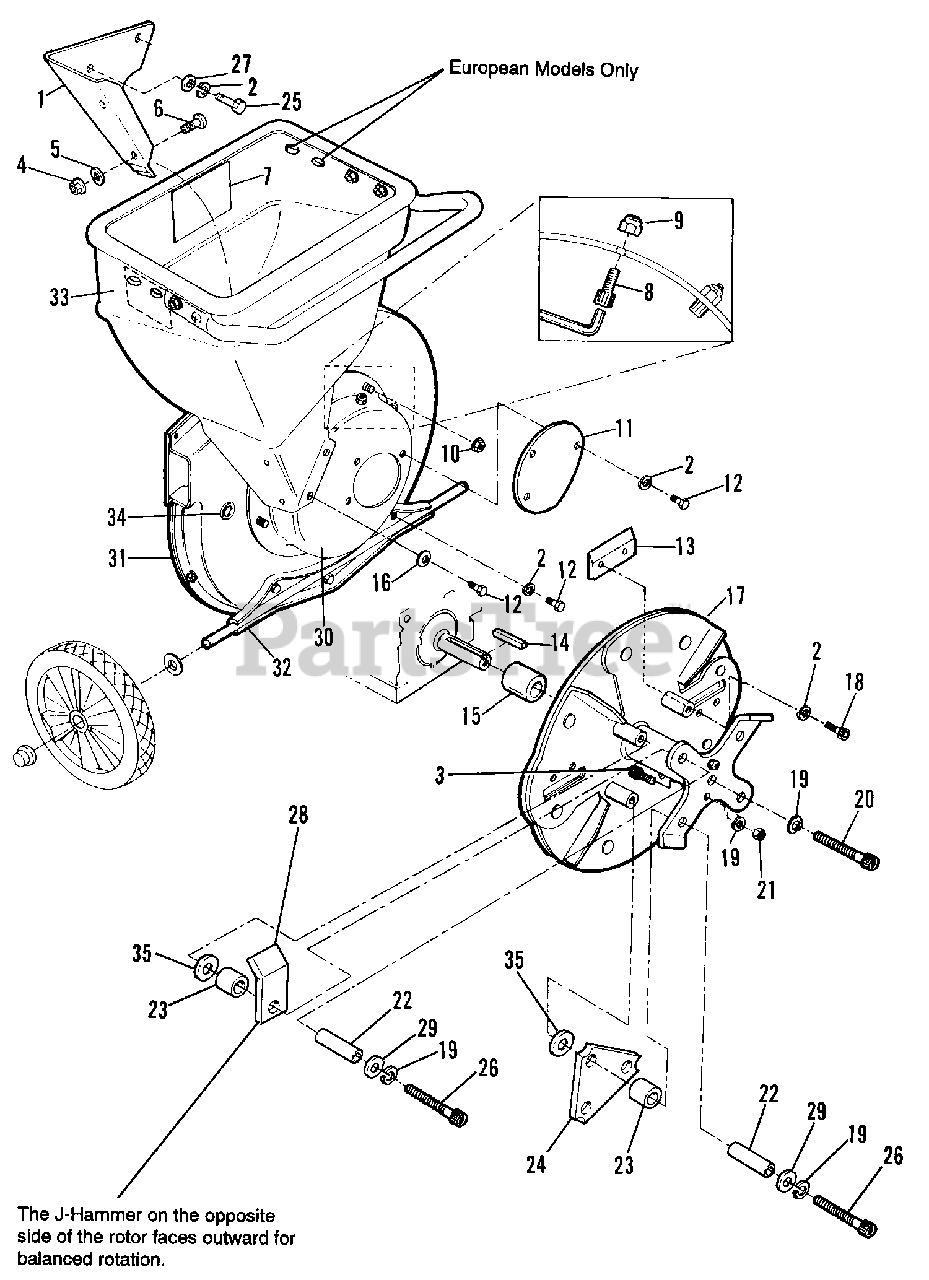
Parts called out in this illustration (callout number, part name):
1	HOPPER LINER
2	* Lockwasher, Split, 5/16
3	CAPSCREW, Socket Hd., 3/8-16 x 5/8
4	NUT, 2-way Lock, 1/4-20
5	WASHER, Flat, 1/4
6	CAPSCREW, Phillips Hd., 1/4-20 x 5/8
7	DECAL, Caution
8	CAPSCREW, Socket Hd., 5/16-18 x 1/2
9	NUT, Hex Lock ESNA Light, 5/16-18
10	NUT, Flange, Hex, 5/16-18
11	COVER, Rotor Housing
12	CAPSCREW, Hex Hd., 5/16-18 x 1/2
13	CHIPPER KNIFE
14	KEY, 1/4 Sq. x 1-7/8
15	SPACER, Rotor (5/14 Only)
15	SPACER, Rotor (8/14 Only)
16	WASHER, Flat, 5/16
17	* ROTOR, 1" Hub
18	CAPSCREW, Socket Hd., 5/16-24 x 5/8
19	* LOCKWASHER, Split, 3/8
20	CAPSCREW, Socket Hd., 3/8-24 x 2
21	NUT, Hex, 3/8-16
22	* SPACER, Tube
23	* SPACER, 3/4" O.D., 3/4" Long (5/14 Only)
23	* SPACER, 1"0.D., 33/64"Long (8/14 0nly)
24	HAMMER, Triangular
25	CAPSCREW, Hex Hd., 5/16-18 x 3/4
26	* CAPSCREW, Hex, Socket Hd., w/Patch, 3/8 16 x 2, Gr. 8
27	WASHER, Flat, 5/16
28	J HAMMER
29	* WASHER, Flat, 7/8 O.D.
30	HOUSING, Rotor
31	HOUSING, Fan
32	AXLE ASSEMBLY
33	DECAL Danger
34	Plug BUTTON
35	WASHER, Plain, 1/2 x 1-1/4 x 3/16 (8/14 0nly)
